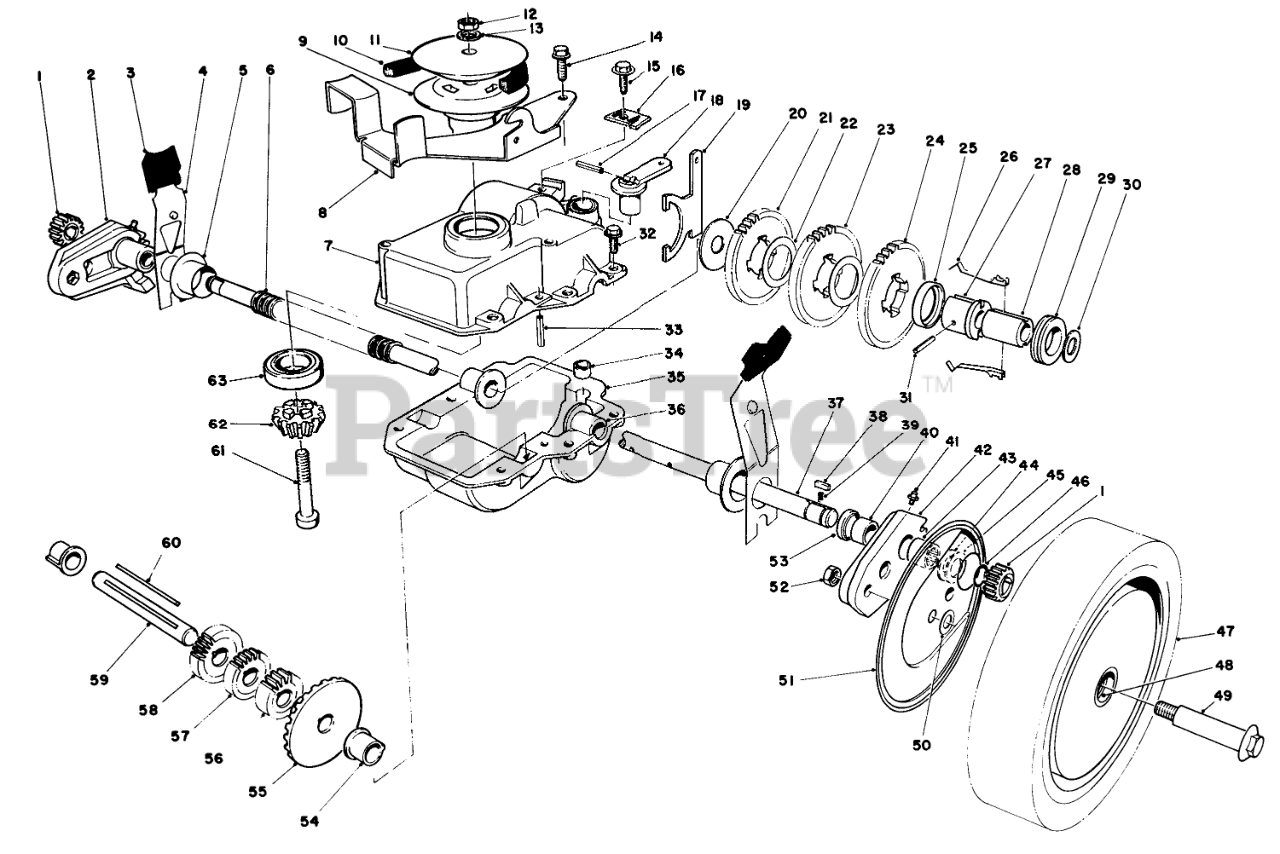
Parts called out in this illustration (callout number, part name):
1	GEAR-PINION
2	Pivot Arm Assembly-R.H. (Incl. Ref. #40, 41, 43 & 53)
3	KNOB-ARM
4	SPRING ARM ASM SP
5	CAP-END
6	CONDUIT-CONVOLUTED, SPLIT
7	Case-Upper
8	BELT GUIDE BRKTB
9	PULLEY-LOWER HALF
10	V-BELT
11	PULLEY-UPPER HALF
12	NUT-LOCK, NI
13	WASHER-FLAT
14	SCREW
15	SCREW-HWHTF
16	Cable Clamp
17	PIN-COIL
18	LEVER-SHIFT
19	Shift Yoke
20	WASHER
21	GEAR-38T
22	WASHER
23	GEAR-42T
25	KEY RETAINER
26	KEY-SHIFT
27	Body-Sleeve
28	SLEEVE
29	COLLAR-SHIFT
30	WASHER-PLAIN
31	PIN-SPRING
32	SCREW-HWHTF
33	ROLL PIN 3/16 X 1 IN
34	BUSHING-YOKE
35	LOWER GEAR CASE CAST
36	Bushing-Output Shaft
37	Output Shaft
38	KEY RECTANGULAR
39	SPRING-COMPRESSION
40	BUSHING
41	FITTING-GREASE
42	Pivot Arm Assembly-L.H. (Incl. Ref. #40, 41, 43 & 53)
43	BEARING-ROLLER
44	INNER THRUST WASHER
45	WASHER-THRUST, OUTER
46	RING-RETAINING
47	Wheel, Tire & Gear Assembly (Incl. Ref. #48)
48	BUSHING
49	WHEEL BOLT
50	WASHER
51	WHEEL COVER
52	NUT-LOCK
54	BUSHING
55	BEVEL GEAR
56	GEAR-12T
57	GEAR-14T
58	GEAR-18T
59	INTERMEDIATE SHAFT
60	Key Square
61	Screw-Socket Hd
62	BEVEL PINION
63	BEARING-BALL
